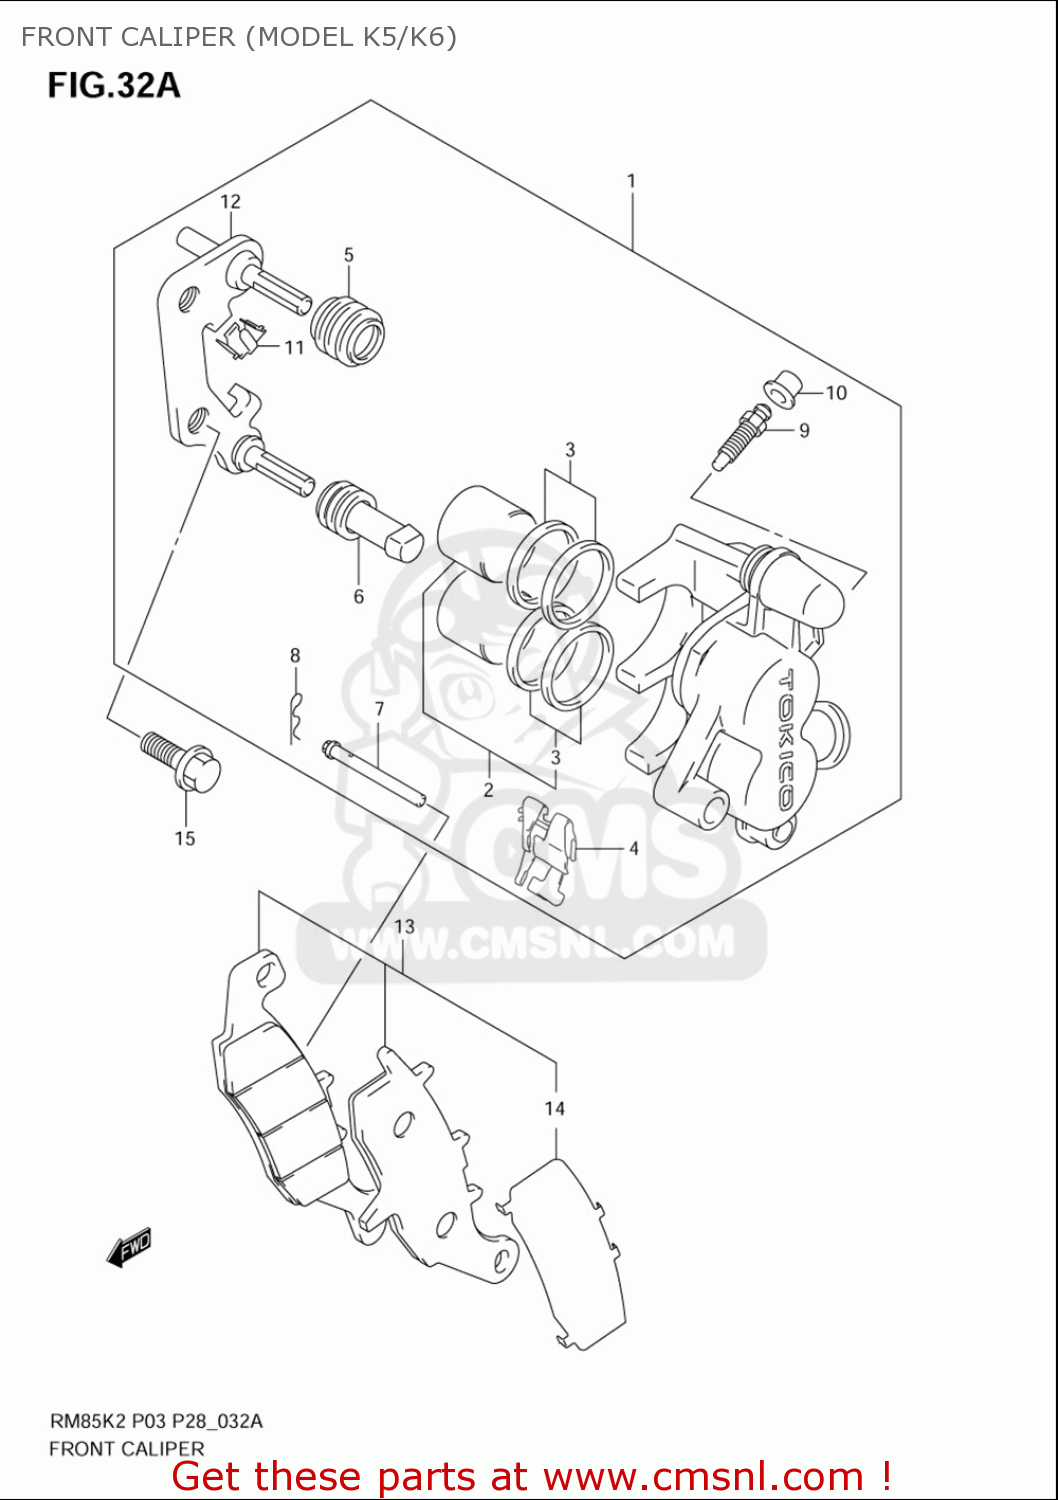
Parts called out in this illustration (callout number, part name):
1	CALIPER ASSY,FR
2	PISTON SET
3	SEAL SET,PISTON
4	SPRING,PAD
5	BOOT,AXLE
6	INSULATOR,AXLE
7	PIN,PAD
8	CLIP,PAD PIN
9	BLEEDER
10	CAP,BLEEDER PLUG
11	GUIDE,PAD
12	CARRIER,CALIPER,L
13	PAD & SHIM SET (NAS)
14	SHIM,PAD
15	BOLT(8X32)
